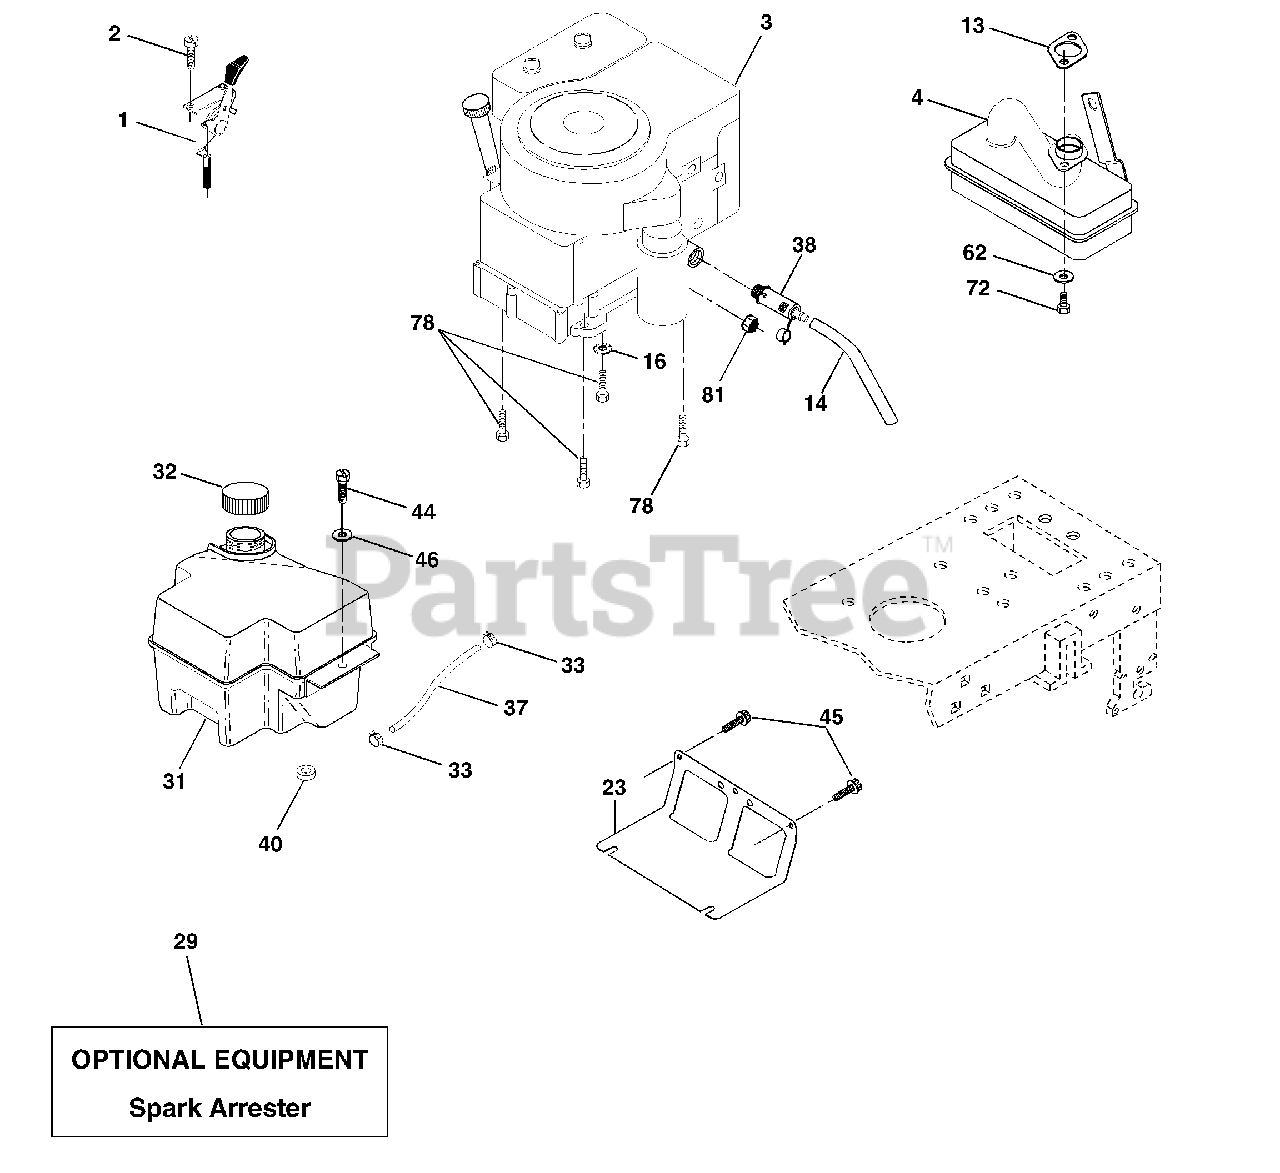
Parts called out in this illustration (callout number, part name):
1	Control Throt/Ch
2	Screw Hex Thd Cut 1/4-20x5/8 T
4	Muffler Tec 13.5/17 Lt
13	Gasket
14	Tube Drain Oil Easy
16	Washer Lock Ext Tooth 3/8
23	Shield Browning
29	Arrestor Spark
31	Tank Fuel 2.00 Fr
32	Cap Fuel Guage
33	Clamp Hose Blk
37	Line Fuel 20"
38	Plug Drain Oil Easy
40	Bushing Snap Nyl Blk Fuel Line
44	Screw Hexwsh Thdrol 1/4-20x3/4
45	Screw 5/16-18 x 3/4
46	Washer 9/32 X 7/8 X 16ga
62	Washer Lock Hvy Hlcl Spr 5/16
78	Screw 3/8-16x1-1/4
81	Nut Flange 1/4-20 Starter Nut
85	Bolt Hex Hd Phillips
